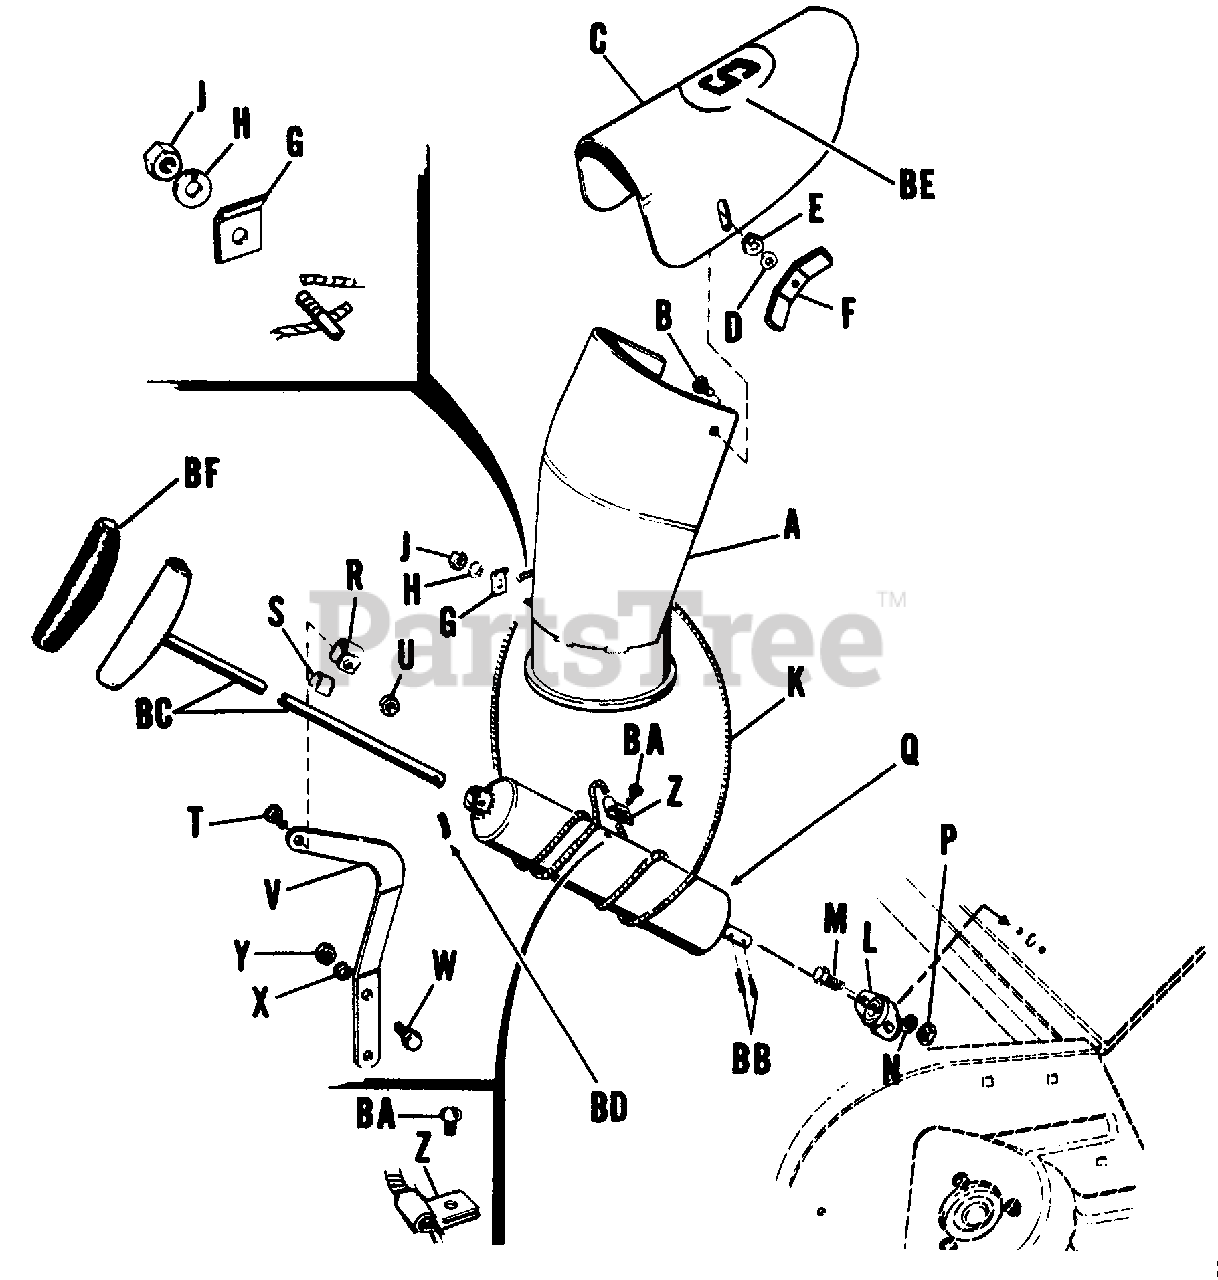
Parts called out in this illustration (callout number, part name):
A	Spout Assembly
B	Carriage Bolt, 5/16"-18 x 3/4" lg.
C	Spout Extension
D	Plain Washer, 3/8"
E	Lock Washer, Special Hexagon, 3/8"
F	NUT, Wing, 5/16-18
H	Lock Washer, 5/16"
J	Hex Nut, Full, 5/16"-18
K	Spout Cord
M	Hex Capscrew, 1/4"-20 x 5/8" lg.
N	Lock Washer, 1/4"
P	Hex Nut, Full, 1/4"-20
Q	Spout Control Tube Assembly
S	Guide Liner
T	Hex Capscrew, 5/16"-18 x 1-1/2" lg.
U	Hex Lock Nut, Full, 5/16"-18
V	Rod Guide Support
W	Hex Capscrew, 3/8"-16 x 1" lg.
X	Lock Washer, 3/8"
Y	Hex Nut, Full, 3/8"-16
BA	Self Tapping Screw, 1/4"-20 x 3/8" lg.
BB	Cotter Pin, 1/8" x 3/4" lg.
BC	Handle Assembly
BD	Cotter Pin, 5/32" x 1"
BF	Cover Handle
